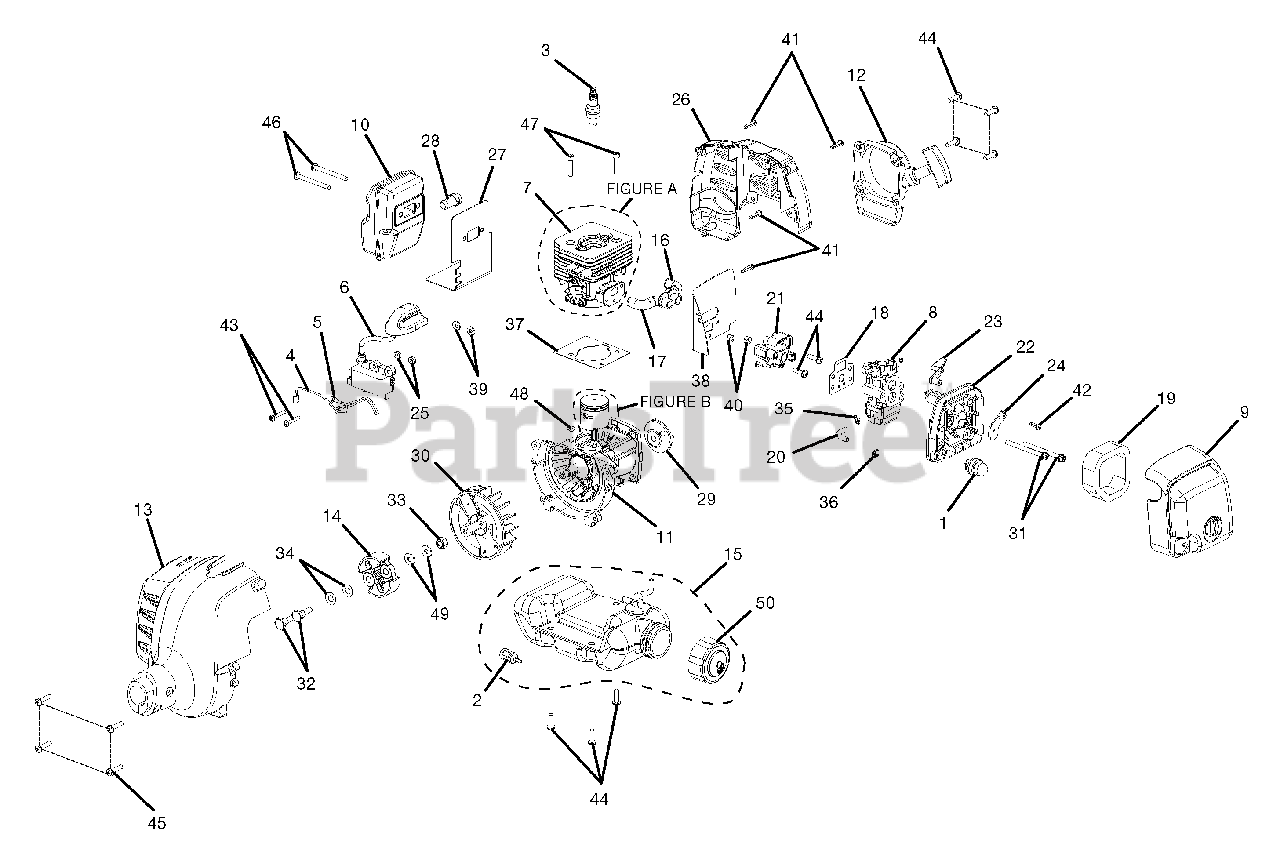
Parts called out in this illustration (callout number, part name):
1	Primer Assembly
2	Fuel Filter
3	Spark Plug
4	Lead Assembly, Black
5	Lead Assembly, Red
6	Coil, Boot, Assembly
7	Cylinder Assembly
8	Carburetor Assembly
9	Cover Assembly
10	Muffler Assembly
11	Crankcase Assembly
12	Starter Recoil Assembly
13	Front Housing Assembly
14	Clutch Assembly
15	Fuel Tank Assembly
16	Pipe, Air, Starter Side
17	Pipe, Air, Flywheel Side
18	Carburetor Gasket
20	Tubing, Plastic Rubber
21	Insulator, Heat Dam
22	Carburetor Plate
23	Choke Lever
24	Choke Plate
25	Ignition Coil Spacer
26	Engine Housing,Rear
27	Muffler Gasket
28	Spark Arrester
30	Rotor, Permanent Magnet
31	Screw(M5 x 0.8 x60 mm, Slotted Recessed Pan Head Machine)
32	Clutch Screw
33	Rotor Nut
34	Curved Washer
35	Hose Clip
36	Hose Clip
38	Insulator Gasket
39	Type A, Plain Washer (3/16 x 7/16 x 3/64, Steel, Zink)
40	Nut, (M5 x .8 mm) Black Oxide
41	Screw (M4 x 1.75 x 16 mm, Type TT, Slotted Recessed Pan HD.)
42	Screw (M4 x 1.75 x 12 mm, Type TT, Slotted Recessed Pan HD.)
43	Screw (M4 x 0.7 x 22 mm, Torx Recessed Pan HD. Machine)
44	Screw (M5 x 0.8 x 16 mm, Torx Recessed Pan HD. Machine)
45	Screw (M5 x 0.8 x 20 mm, Torx Recessed Pan HD. Machine)
46	Screw (M5 x 0.8 x 50 mm, Torx Recessed Pan HD. Machine)
47	Screw (M5 x 0.8 x 22 mm, Socket HD. Cap, Black Oxide)
48	Woodruff Key (10 mm x 3.7 mm x 3 mm)
50	Fuel Cap
